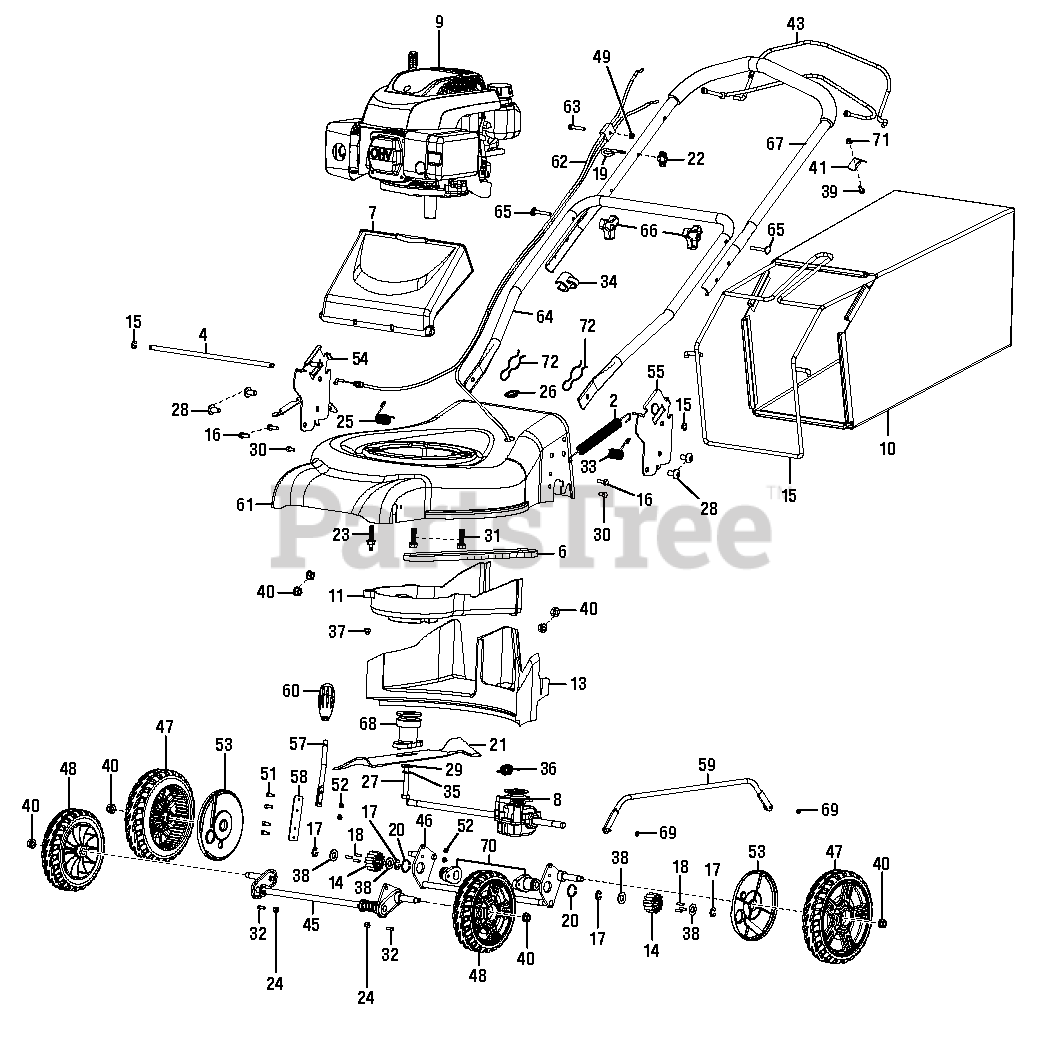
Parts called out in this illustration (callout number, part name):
4	Door Hinge Rod
8	Transmission
9	Engine (140cc OHV)
10	Grass Catcher
13	Rear Baffle
14	Pinion Gear
15	Door Hinge E-Ring
16	Screw (1/4 in. x 3/4 in., Hex Hd.)
17	Pinion E-Ring
20	Retaining Ring (1 in.)
21	Mower Blade (18 in.)
23	Engine Bolt, 2 End
24	Lock Nut (#10)
25	Door Spring (RH)
27	Blade Bolt (3/8-24 x 2.5 in.)
28	Socket Screw (M10, Button Hd.)
30	Screw (M6 x 13 mm, Hex Hd.)
31	Engine Bolt
32	Screw (#10 x 1/2 in.)
33	Door Spring (LH)
34	Cable Clamp
35	Lock Washer (3/8 in.)
36	Tension Spring
38	Seal Washer
39	Bolt (M5 x 30 mm)
45	Front Axle Assembly
46	Rear Torque Assembly
47	Drive Wheel Assembly
48	Wheel Assembly (7 in.)
49	Flange Nut (M6)
51	Screw (M5 x 13 mm, Socket Hd. Cap)
52	Flange Nut (M5)
53	Wheel Dust Cover
54	Handle Bracket Assembly (RH)
55	Handle Bracket Assembly (LH)
57	Handle Adjustment Rod
58	Handle Adjustment Plate
59	Height Adjustment Assembly
60	Height Adjustment Knob
61	Deck Assembly (45 cm)
62	Cable Mzr. Drive Assembly
63	Bolt (M6 x 35 mm, Flange Head)
64	Lower Handle
65	Square Handle Screw
66	Handle Knob
67	Upper Handle Assembly
68	Blade Adapter Assembly
69	Flange Nut (M5)
70	Axle Bushing Assembly
71	Flange Nut (M5)
72	Handle Clip
